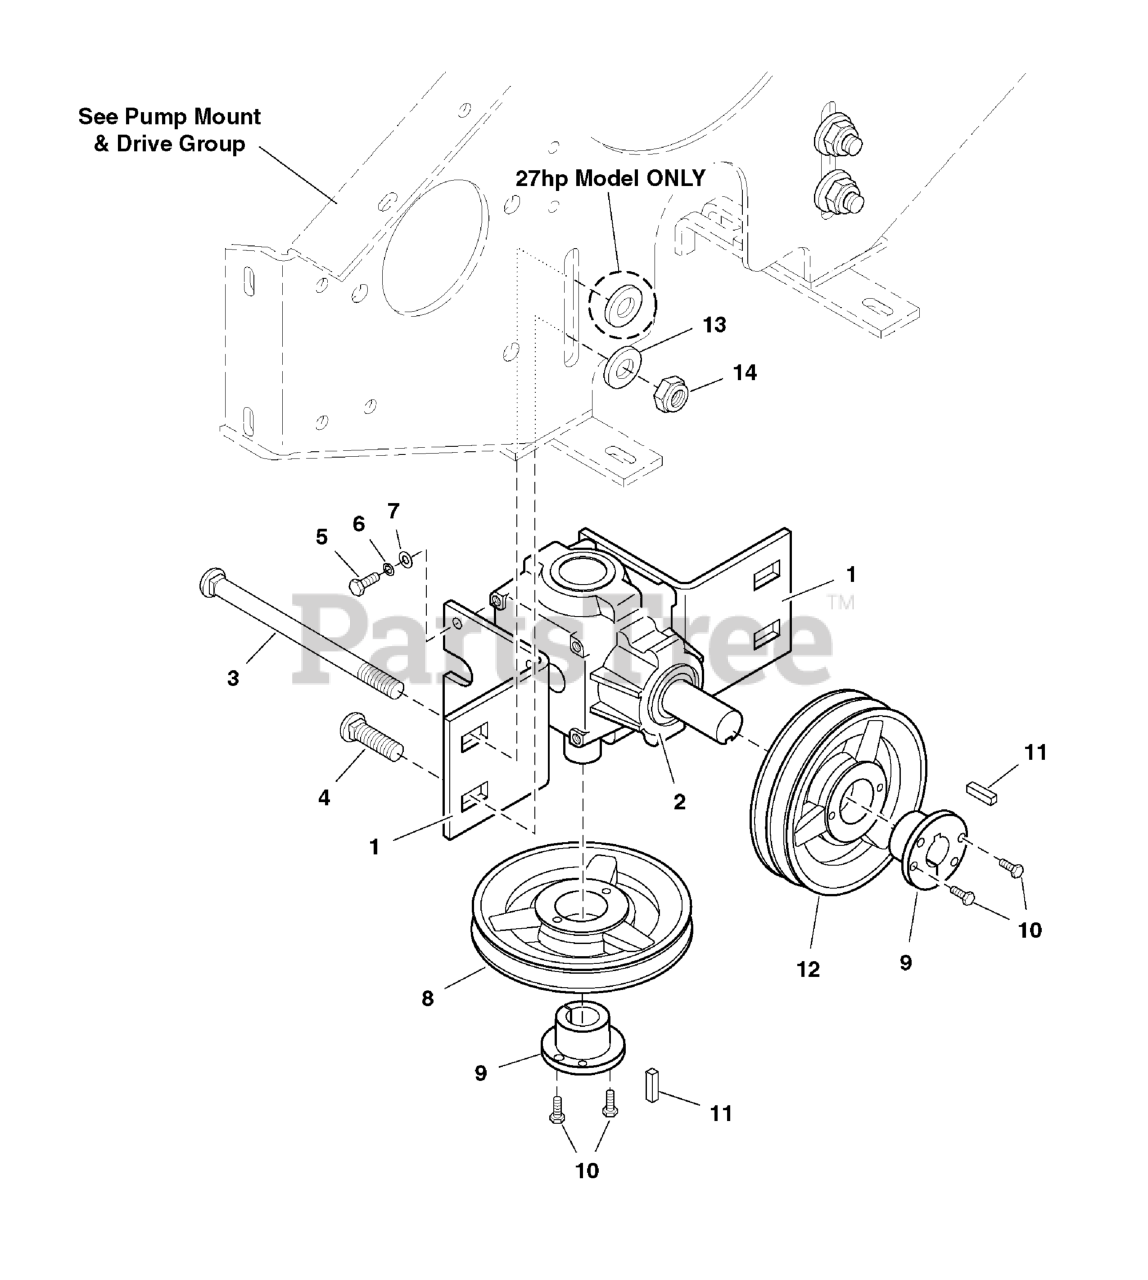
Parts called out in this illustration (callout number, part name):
1	GEARBOX MOUNT BRACKET
2	GEARBOX
3	CARRIAGE BOLT, 1/2-13 x 7
4	CARRIAGE BOLT, 1/2-13 x 2
5	BOLT, 5/16-18 X 1 GD5 YZ
6	WASHER, 5/16 LOCK CZ
7	WASHER, 5/16" SAE
8	PULLEY, Spindle
9	BUSHING, Tapered Hub
10	BOLT, 1/4-20 X 1" GD5 CZ
11	KEY, 1/4 SQ. X 1
12	PULLEY, Gearbox Input
13	WASHER, Frame Retaining
14	NUT, 1/2-13 Hex
